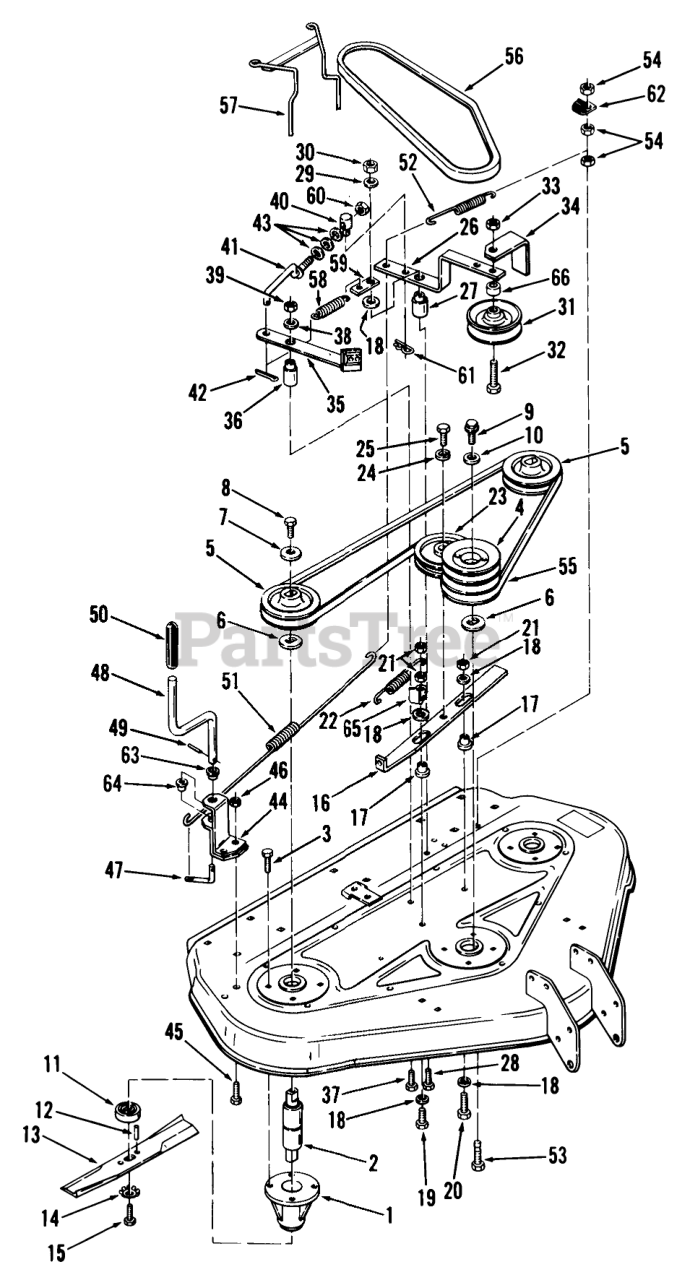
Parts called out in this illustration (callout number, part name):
1	HOUSING-BEARING B
2	BEARING
3	Bolt
4	PULLEY-36IN MOWER
5	PULLEY-MOWER DRIVE
6	WASHER-DOUBLE D
7	WASHER
8	Bolt
9	Bolt-Lock 3/8-16 x 7/8
10	Washer
11	Cup-Spindle
12	SPIROL ROLL PIN
13	BLADE KIT 36 LF REAR
14	WASHER
15	Bolt
16	BAR-IDLER SUPPORT
17	Bushing/Spacer
18	WASHER
19	Bolt
20	Bolt
21	Nut
22	SPRING-EXTENSION
23	Idler Pulley
24	LOCKWASHER
25	BOLT HEX SPECIAL
26	Idler Arm
27	Pivot Bushing
28	Bolt
29	Washer
30	Nut
31	IDLER PULLEY
32	Bolt
33	Nut
34	Belt Guide
35	ASSY-BRAKE
36	Pivot Bushing
37	Bolt
38	WASHER
39	Nut
40	TRUNNION-LIFT
41	Brake Rod
42	Pop Rivet
43	WASHER-NYLON
44	Pivot Bracket
45	Bolt
46	Nut
47	Engagement Bar
48	LEVER-ENGAGEMENT
49	Pin-Roll
50	GRIP
51	SPRING-ENGAGEMENT
52	SPRING-RETURN
53	Bolt
54	Nut
55	V-BELT
56	V-BELT
57	Belt Guide
58	Spring
59	Spring Tab
60	NUT
61	Hairpin Cotter
62	CLIP
63	NYLINER BUSHING
64	BUSHING-NYLINER
65	SPACER-BRACKET
66	Spacer
